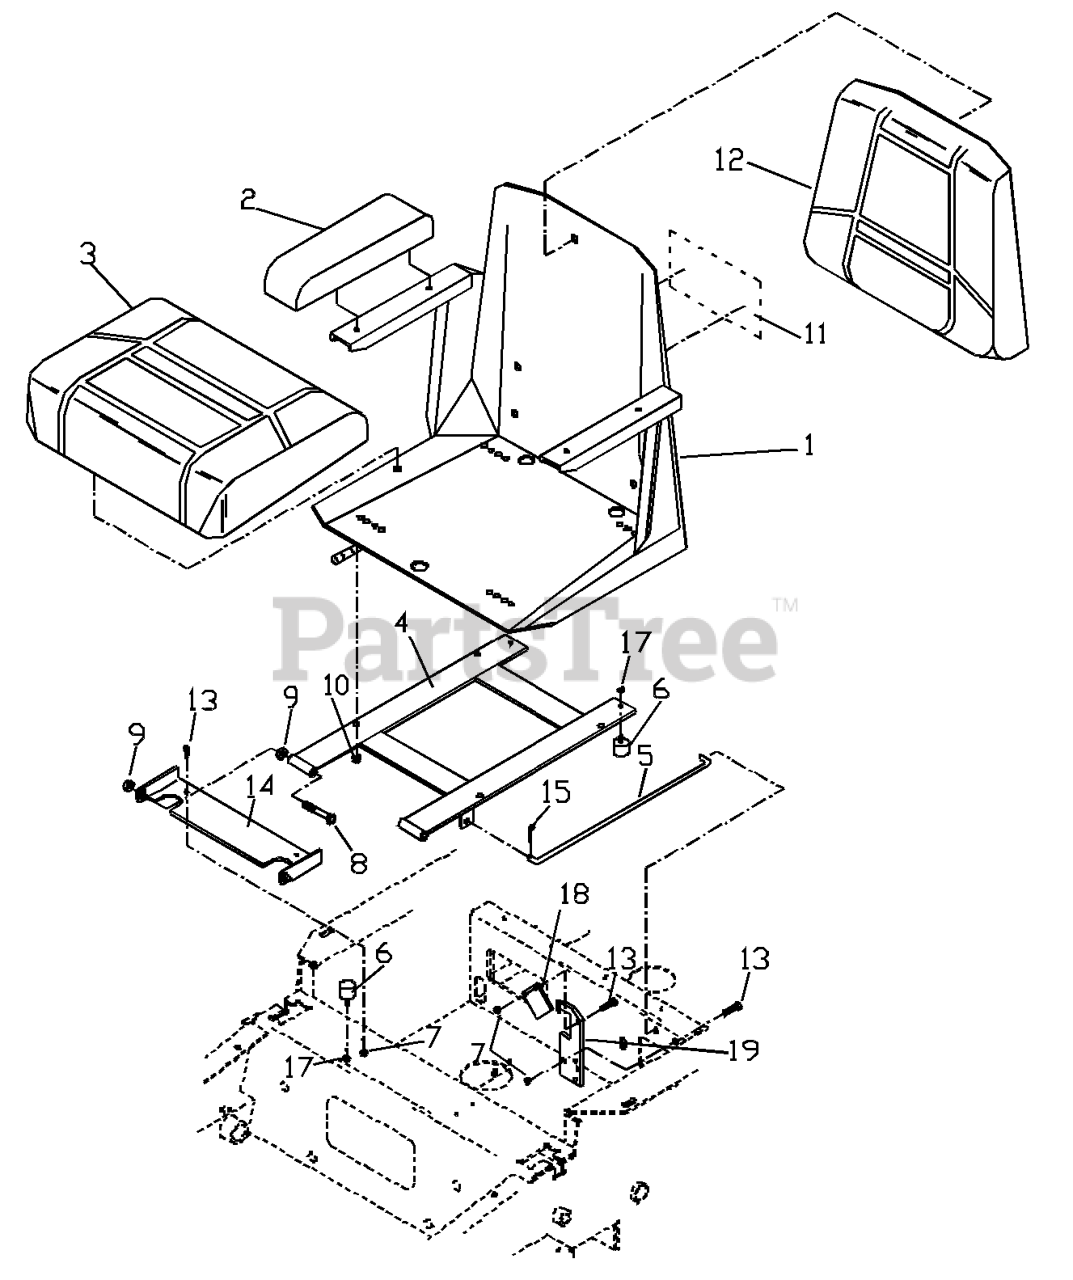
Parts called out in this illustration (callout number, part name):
1	SEAT, COMPLETE
2	ARM REST CUSHIONS/PAIR
3	SEAT CUSHION W/SWITCH
4	SEAT MOUNT
6	STUD/PLATE MOUNT
7	NUT 1/4C CENTER LOCK
8	HCS 3/8C X 3
9	NUT 3/8C CENTERBLOCK
10	NUT 5/16 NYLOC
11	DECAL, CROWN H
12	SEAT, BACK CUSHION
13	HCS 1/4C X 3/4 HCS
14	SEAT BRKT W/DECAL
15	RP_COTTER PIN 1/8 X 3/4
17	NUT.1/4-20.HEX.NYLOC.ZD
18	SEAT LATCH
19	SEAT LATCH BASE
